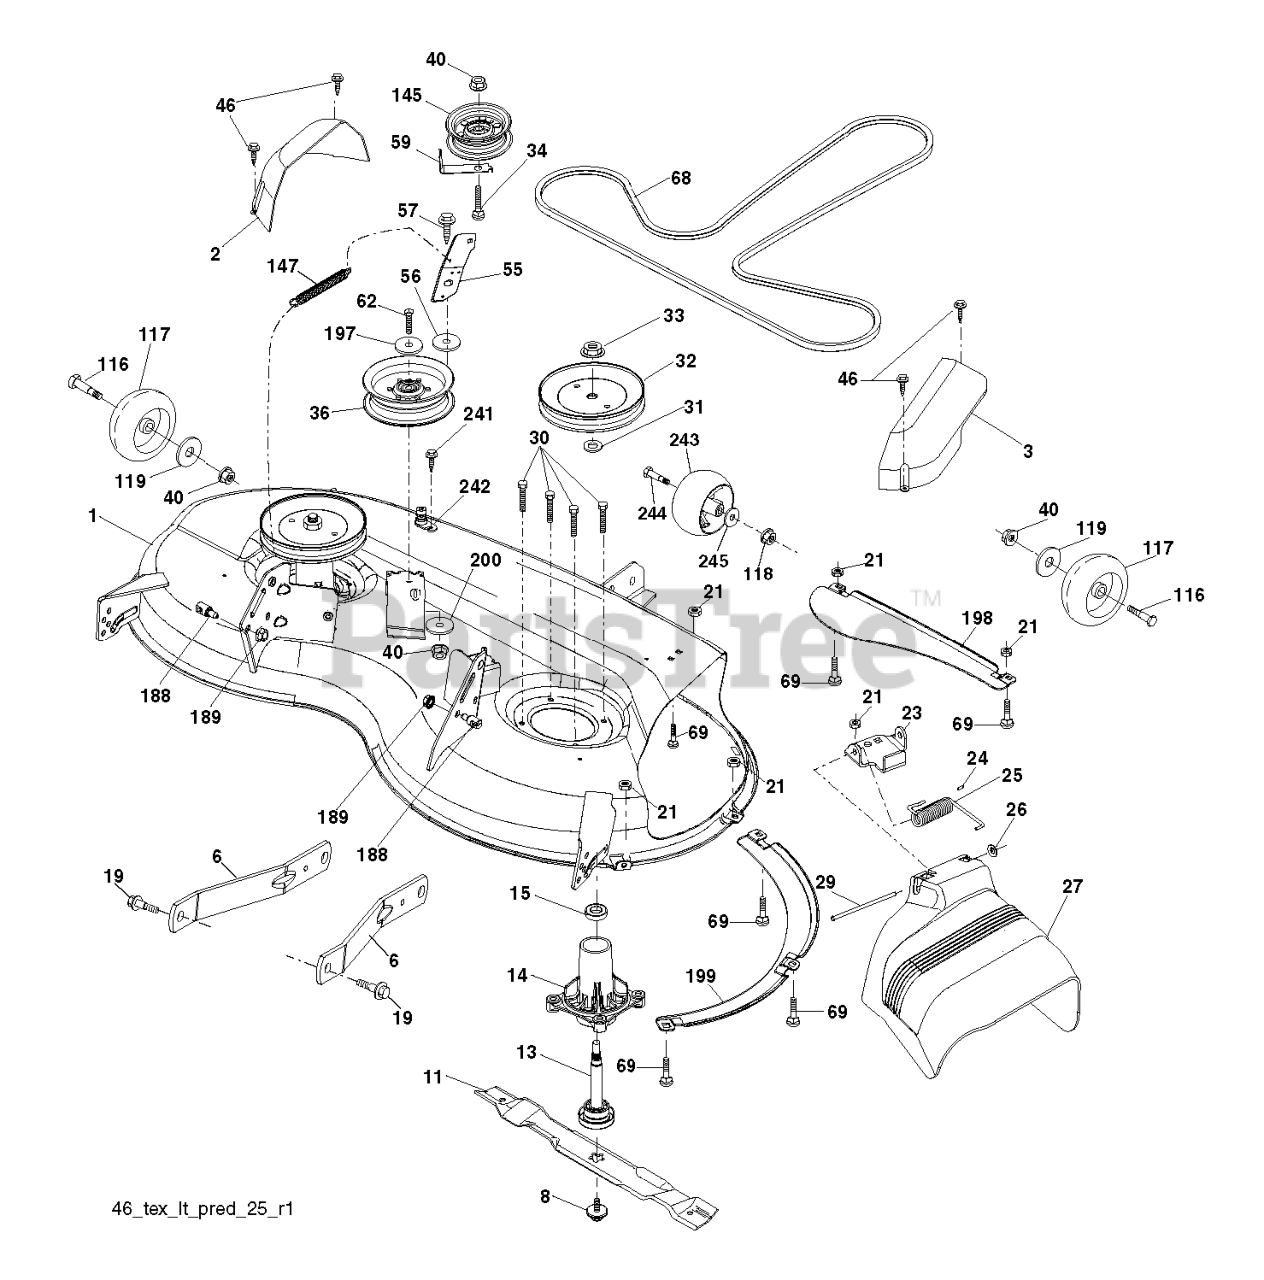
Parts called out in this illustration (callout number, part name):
1	DECK.WLDMT.WTUBES.46.4GWB.ORNG
2	COVER.MANDREL.LH.46"
3	COVER.MANDREL.RH.46"
6	ARM.SUSPENSION.MOWER.R
8	BOLT.WASHER.ASM.7/16-2
11	BLADE.MOWER.46".HI.LIFT
13	SHAFT.ASM.MDRL.N/GREASE.38
14	RP.HOUSING.MANDREL.4PT.
19	BOLT.SHOULDER
21	LOCKNUT
23	BRKT.DEFLECTOR.38"2005+
24	CAP-SLEEVE LT
25	SPRING.TORSION.DEFLECT
26	NUT PUSH M
27	SHIELD.DEFLECTOR.MOWER.46"BLAC
29	ROD.HINGE
30	SCREW, WASHER HEAD
31	WASHER.SPACER.MANDREL
32	PULLEY.MANDREL.5.438.PD
33	NUT.FLANGE.LOCK.TOP
34	BOLT.3/8-16X1.50
36	PULLEY.IDLER.2006
40	NUT LOCK FLG 3/8-16 UNC
46	SCREW.1/4-20X5/8
56	SPACER.RETAINER
57	SCREW 3/8-16X1
59	GUARD, BELT
62	BOLT-HEX EAK
68	V-BELT
69	BOLT
116	BOLT.SHOULDER.3/8-16X3-5/8.
117	RP WHEEL. GUAGE RALLY
118	NUT LOCK FLG 3/8-16 UNC
119	WASHER
145	PULLEY.IDLER.48"PRIMARY
147	SPRING.MOWER.DRIVE.ELECTRIC
188	STUD.FASTNER.W/ANTI-ROTATE
189	NUT LOCK HEX FLANGE 5/16-18
197	WASHER
198	BAFFLE CENTER FRONT
199	BAFFLE FRONT RH
200	WASHER.13/32 X 1 X 1/2.11GUARD
241	SCREW.TT.#10-32X.5.3/8.FLANGE
242	PORT.WASHOUT
243	WHEEL.GAGE.HALF.SPOKED
244	BOLT M
245	WASHER.5/16.FLAT.STE.STD.
245	COUPLING.QUICK CONNECT
245	MANDREL.ASM.SUB-NON.GR
245	DECK.ASM SVC 46"HP E 5GW WP668
